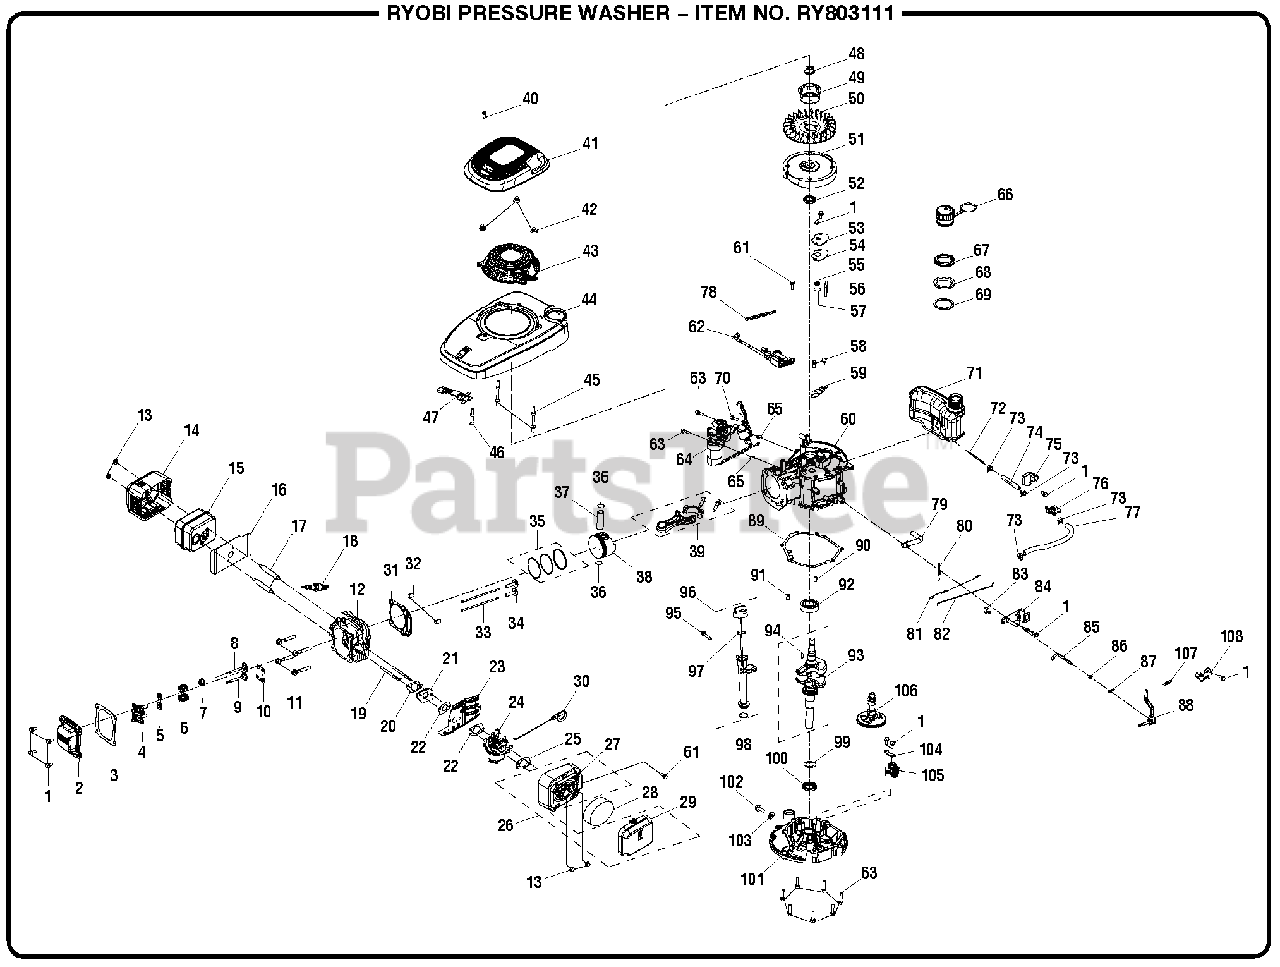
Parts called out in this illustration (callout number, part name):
1	Bolt (M6 x14 mm)
2	Valve Cover
3	Valve Cover Gasket
4	Rocker Arm Assembly
5	Valve Spring Seat
6	Valve Spring
7	Intake Valve Seal
8	Intake Valve
9	Exhaust Valve
10	Rocker Arm Base
11	Bolt (M8 x 54 mm)
12	Cylinder Head
14	Muffler Guard
16	Muffler Gasket
17	Stud (M6 x 95 mm)
19	Stud (M6 x 87 mm)
20	Carburetor Insulator Gasket
22	Carburetor Gasket
25	Air Filter Gasket
26	Air Filter Assembly
27	Air Filter Base
28	Air Filter Element
29	Air Filter Cover
30	Choke Lever
31	Cylinder Head Gasket
34	Tappet Screw
35	Piston Ring Set
39	Connecting Rod Assembly
40	Screw (M4.2 x 25 mm)
41	Blower Housing
43	Recoil Starter
44	Inner Shroud
45	Stud (M6 x 78.5 mm)
46	Stud (M6 x 74 mm)
47	Ground Wire
49	Starter Cup
50	Cooling Fan
53	Breather Cover
54	Oil Filter Gasket
55	Valve Spring
56	Breather Filter Screen
57	Breather Valve
58	Bolt (M6 x 12 mm)
61	Bolt (M6 x 20 mm)
62	Ignition Module
63	Bolt (M6 x 28 mm)
64	Electric Starter
68	Damping Pad
69	Damping Pad
70	Bolt (M6 x 16 mm)
72	Fuel Filter
75	Fuel Switch Base
76	Fuel Switch/100008895
79	Breather Hose
80	Governor Spring
81	Idle Spring
82	Throttle Linkage
84	Governor Gear Bracket Assembly
85	Governor Gear Shaft
88	Governor Lever
89	Crankcase Gasket
92	Bearing (6205)
94	Woodruff Key
95	Bolt (M6 x 35 mm)
97	O-Ring (Dipstick)
98	O-Ring (Dipstick)
101	Crankcase Cover
102	Ground Bolt
104	Governor Gear Mounting Plate
105	Governor Gear
107	Governor Spring
108	Idle Speed Control
